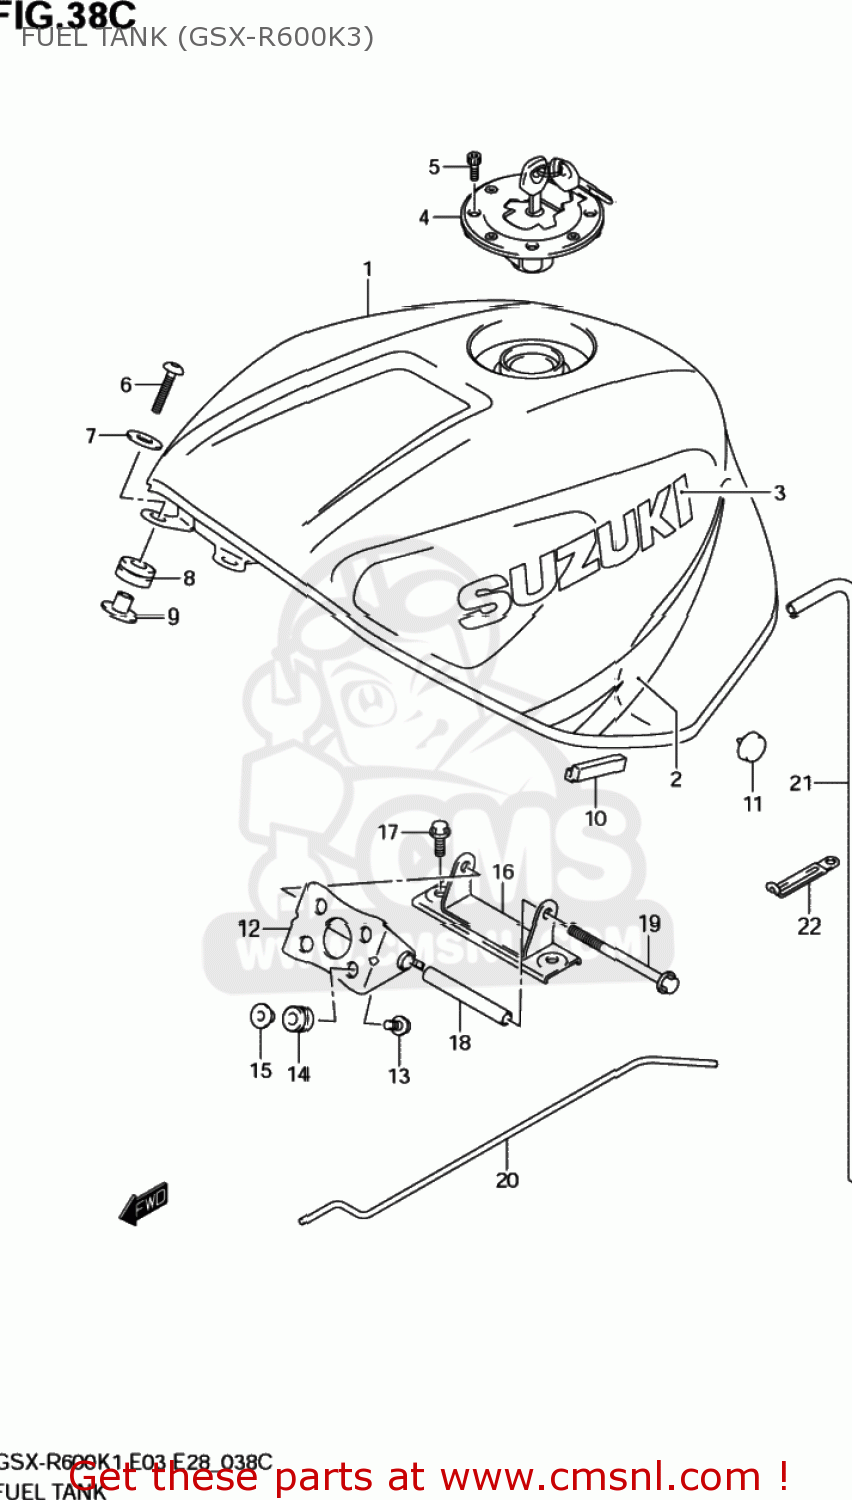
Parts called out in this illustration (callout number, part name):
1	TANK ASSY,FUEL(BLUE)
2	TAPE SET,FUEL TANK
3	EMBLEM,FUEL TANK
4	CAP SET,FUEL TANK
5	BOLT(5X20)
6	SCREW(6X25)
7	WASHER(6.5X22X1.6)
8	CUSHION,FUEL TANK FR
9	SPACER,FUEL TANK FR
10	CUSHION,FUEL TANK SIDE
11	CUSHION,FUEL TANK SIDE NO.2
12	BRACKET,FUEL TANK NO.1
13	BOLT(6X20)
14	CUSHION
15	WASHER
16	BRACKET,FUEL TANK NO.2
17	BOLT
18	SPACER,FUEL TANK RR
19	BOLT
20	STAY,FUEL TANK
21	HOSE,FUEL TANK WATER DRAIN
22	CLAMP(L:65)
